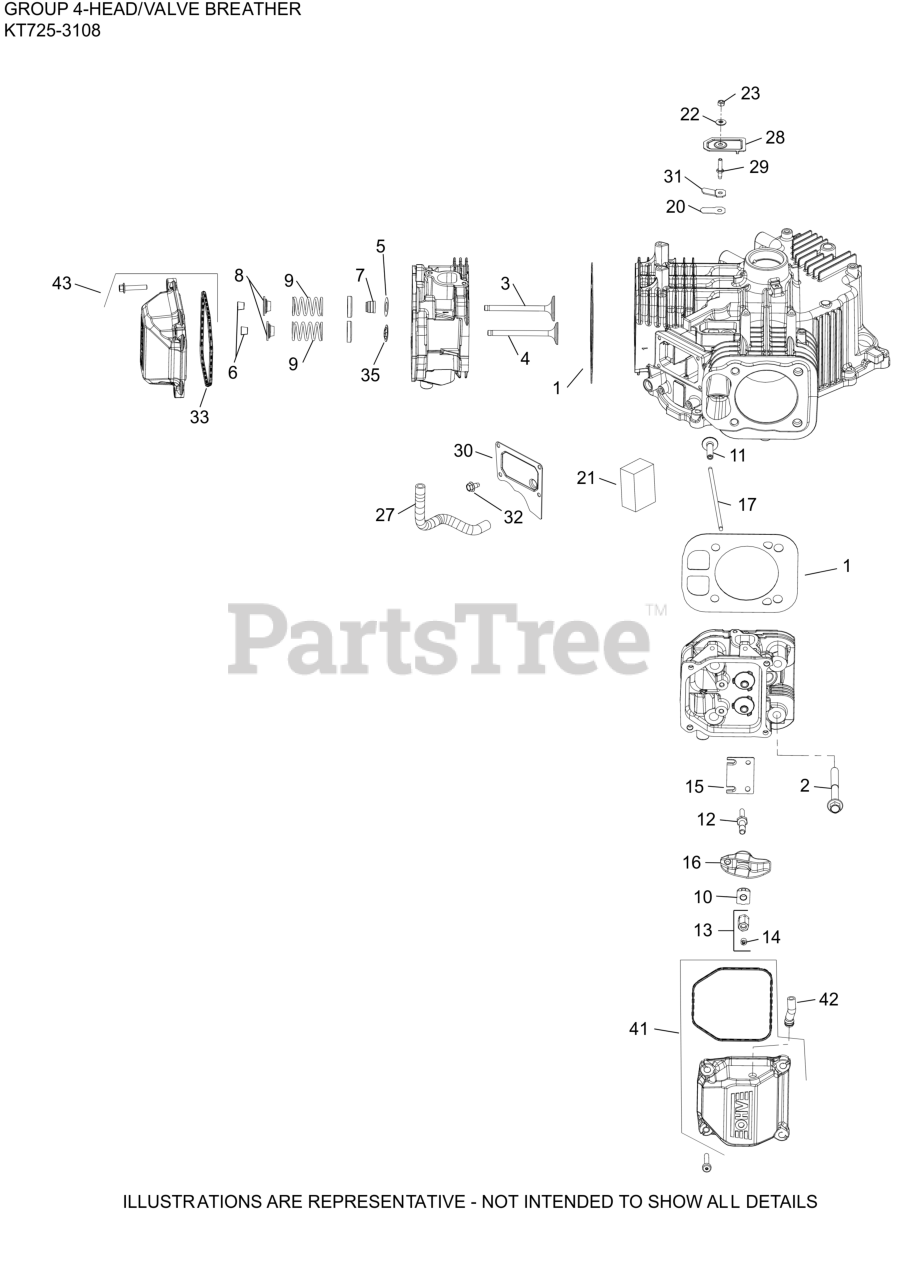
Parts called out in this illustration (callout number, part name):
1	KIT, CYLINDER HEAD GASKET
3	VALVE, INTAKE
3	VALVE, INTAKE (.25) - (#2401702S)
4	VALVE, EXHAUST
4	VALVE, EXHAUST (.25)
5	SPACER (.010")
6	KIT, RETAINER
7	SEAL, VALVE BAND
8	CAP, VALVE SPRING
9	SPRING VALVE
10	PIVOT, ROCKER ARM
12	STUD, ROCKER
13	HEX NUT ASSEMBLY
14	SCREW, SET
15	PLATE, GUIDE
16	ARM, ROCKER
17	ROD, PUSH
20	REED, BREATHER
21	FILTER, BREATHER
22	WASHER, SEALING
23	NUT, LOCK M5X.8
27	HOSE, BREATHER
28	COVER, BREATHER REED
30	COVER, BREATHER MEDIA
31	RETAINER, REED
32	SCREW, THREAD FORMING
33	O-RING (YELLOW), VALVE CO
35	RETAINER, VALVE GUIDE (KM)
41	KIT,BREATHER VALVE COVER (PLASTIC)
42	HOSE, FP-USE 32 326 07-S(PLASTIC COVERS)
43	KIT, VALVE COVER-PLAIN (PLASTIC)
NI	SCREW, HEX FLANGE M10 X 1.5-6g X 90mm
NI	SCREW, HEX FLANGE (M6 X 31.625 DOG PT)
NI	KIT, #1 CYLINDER HEAD
NI	KIT, #2 CYLINDER HEAD
